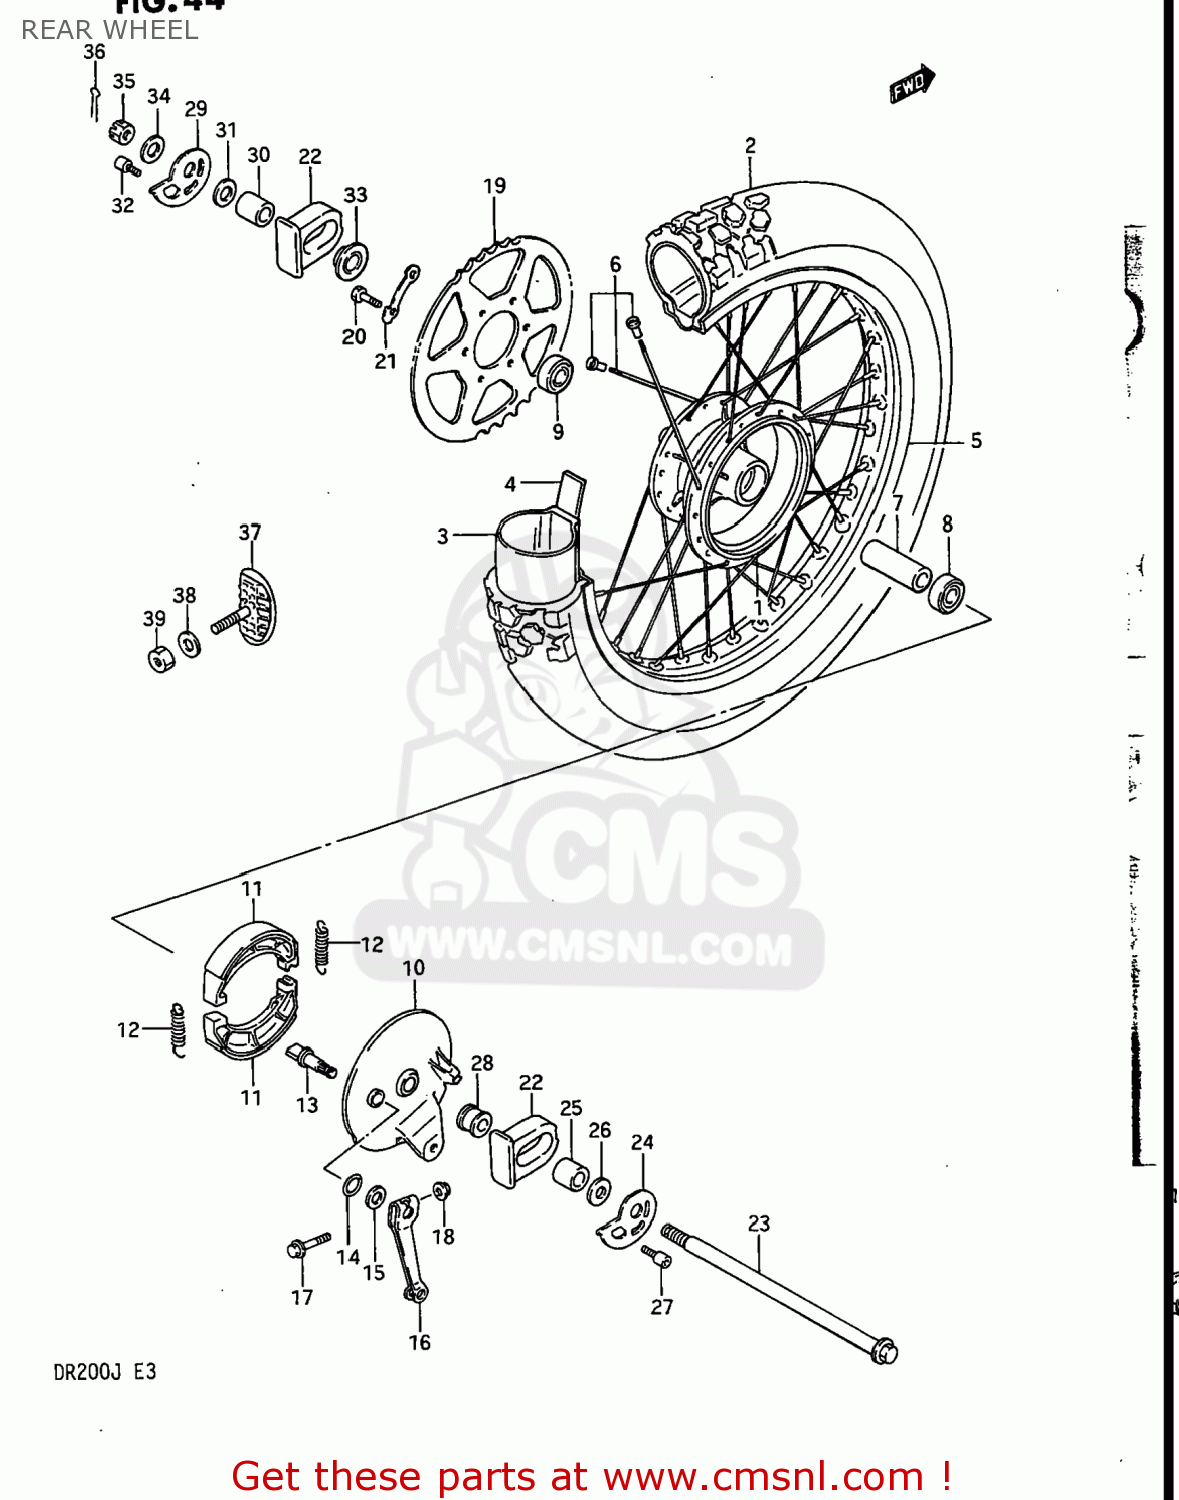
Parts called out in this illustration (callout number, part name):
1	HUB,REAR
2	TIRE,REAR 100/100-18
3	TUBE ASSEMBLY,WHEEL,INNER
4	PROTECTOR,WHEEL,INNER
5	RIM,REAR WHEEL
6	SPOKE SET,RR WHEEL
7	SPACER(15.3X21.7X107.5)
8	BEARING
9	BEARING
10	PANEL,RR BRAKE ANCHOR
11	SHOE,BRAKE
12	SPRING(L:34)
13	CAM,FRONT BRAKE
14	O-RING (D:2.4 ID:13.8)
15	WASHER (14.5X22X1.6)
16	LEVER,RR BRAKE CAM
17	BOLT
18	NUT
19	SPROCKET,REAR
20	BOLT(8X30)
21	WASHER
22	CAP,RR SWINGING ARM
23	AXLE,REAR
24	ADJUSTER,CHAIN,R
25	SPACER,CHAIN ADJUSTER
26	WASHER(15.5X30X3.2)
27	BOLT,CHAIN ADJUSTER
28	SPACER,RR AXLE,R
29	ADJUSTER,CHAIN,L
30	SPACER,CHAIN ADJUSTER
31	WASHER(15.5X30X3.2)
32	BOLT,CHAIN ADJUSTER
33	SPACER,RR AXLE,L
34	WASHER
35	NUT 14MM
36	COTTER PIN
37	STOPPER,BEAD
38	WASHER
39	NUT
